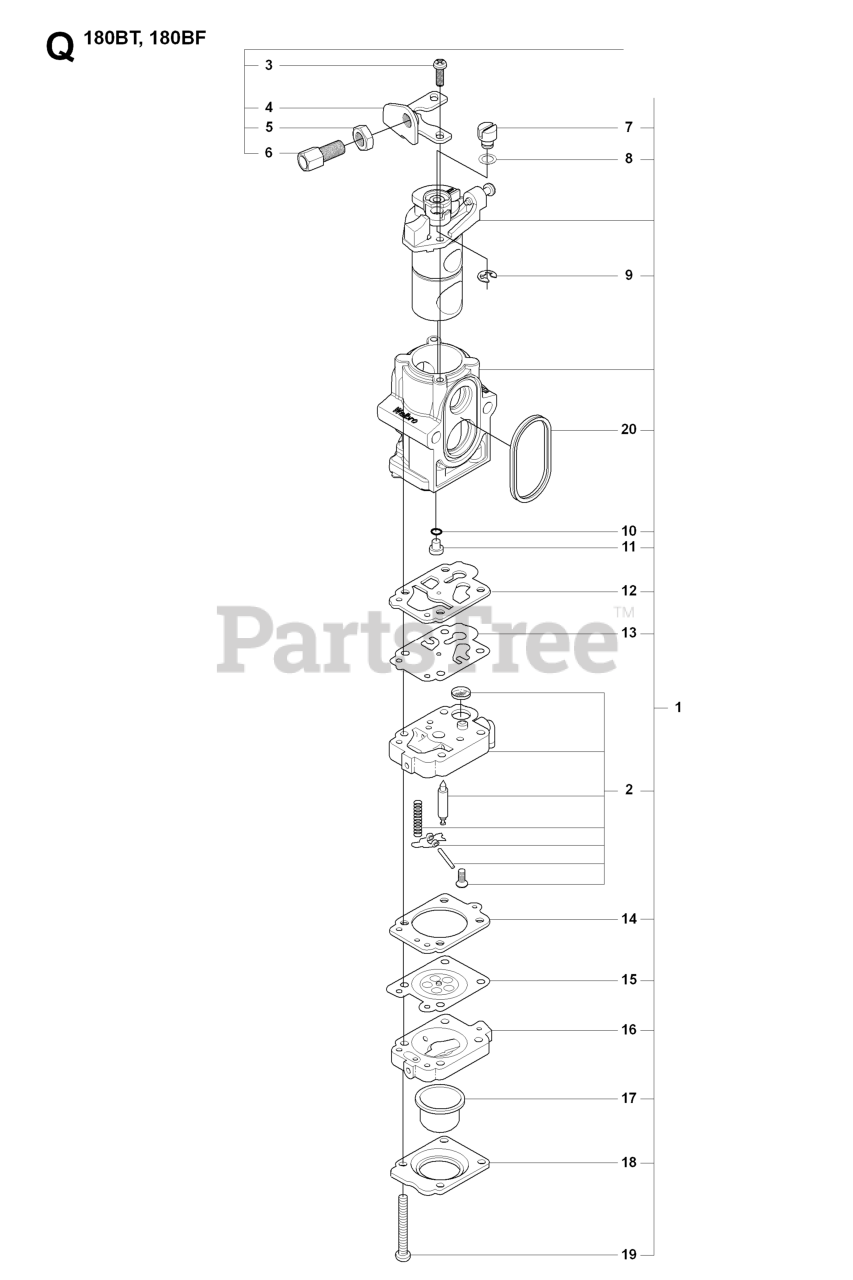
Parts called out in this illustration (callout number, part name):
1	CARBURETOR-A
2	BODY-A-PUMP
3	SCREW
4	RP_BRACKET
5	NUT
6	SCREW
7	SWIVEL
8	WASHER
10	O-RING
12	GASKET
13	DIAPHRAGM
14	GASKET
15	DIAPHRAM
16	DIAPHRAM
17	PUMP
18	COVER
19	SCREW
20	RP RING
